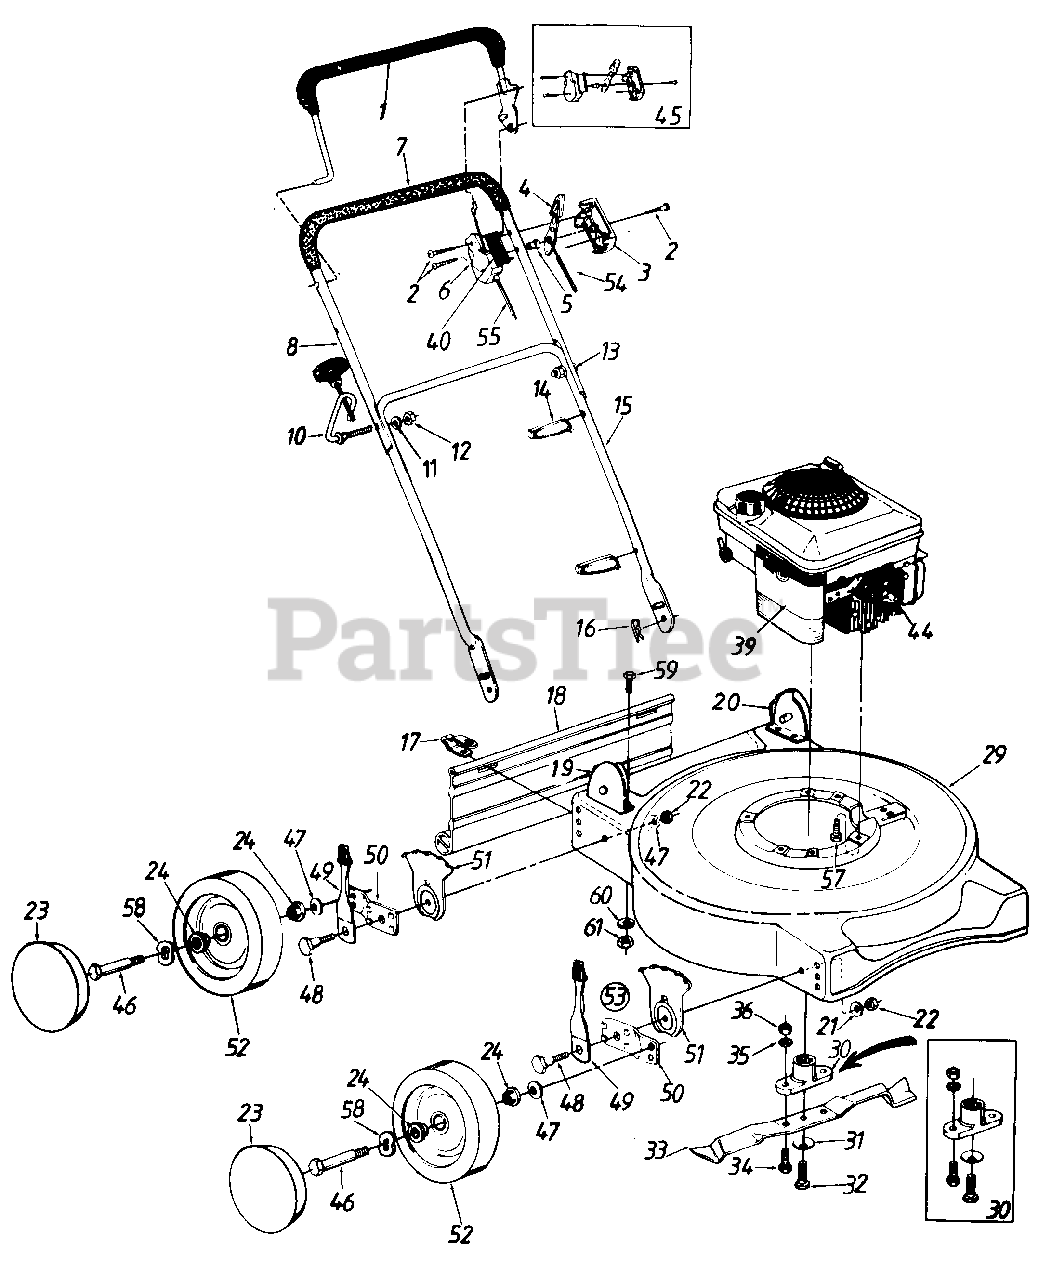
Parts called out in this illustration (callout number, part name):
1	Control Handle Ass'y.
2	Truss Mach. Scr. #12 x 1.5" Lg.
3	Control Panel Half
4	Throttle Control Lever
5	Control Disc Pin
6	Clutch Panel Half
7	Grip
8	Upper Handle
10	Rope Guide Bolt
11	L-Wash. 5/16" I.D.*
12	Hex Nut 5/16-18 Thd.
13	Curved Carriage Bolt 5/16-18 x 1 38" Lg.
14	Cable Tie
15	Lower Handle
16	Hairpin Cotter
17	Hinge Clip
18	Rear Flap
19	Handle Bracket Ass'y.-L.H.
20	Handle Bracket Ass'y.-R.H.
21	Bell-Wash. .39" I.D. x 1.38"
22	Hex Nut 3/8-16 Thd.
23	Hub Cap
24	Ball Bearing
29	20" Deck Ass'y.
30	Blade Adapter Kit (Splined)
31	Bell-Wash. .46" I.D.
32	Hex Bolt 7/16-20 x 1.5" Lg.
33	20" Mulching Biade
34	Hex Bolt 3/8-24 x 1" Lg.
35	L-Wash. 3/8" I.D.
36	Hex Nut 3/8-24 Thd.
39	Engine
40	Throttle Label
44	Spark Plug Boot
45	Kit-Control Housing Comp.
46	Axle Bolt
47	Bell-Wash. .400" I.D. x .88"
48	Shld. Bolt .50" Dia. x .357"
49	Spring Lever Ass'y. w/Knob
51	Height Adj. Plate
52	Wheel Ass'y. Comp.
53	Height Adj. Ass'y. Comp.-R.F. & L.R.
54	Throttle Cable-51"
55	Control Cable-35"
57	Hex L-Wash. Hd. Scr. 3/8-16 x 1.0" Lg.
58	Wave Washer .53" I.D.
59	Hex Bolt 1/4-28 x .75" Lg. (Grade 5)
60	L-Wash. 1/4" I.D.
61	Hex Nut 1/4-28 Thd.
